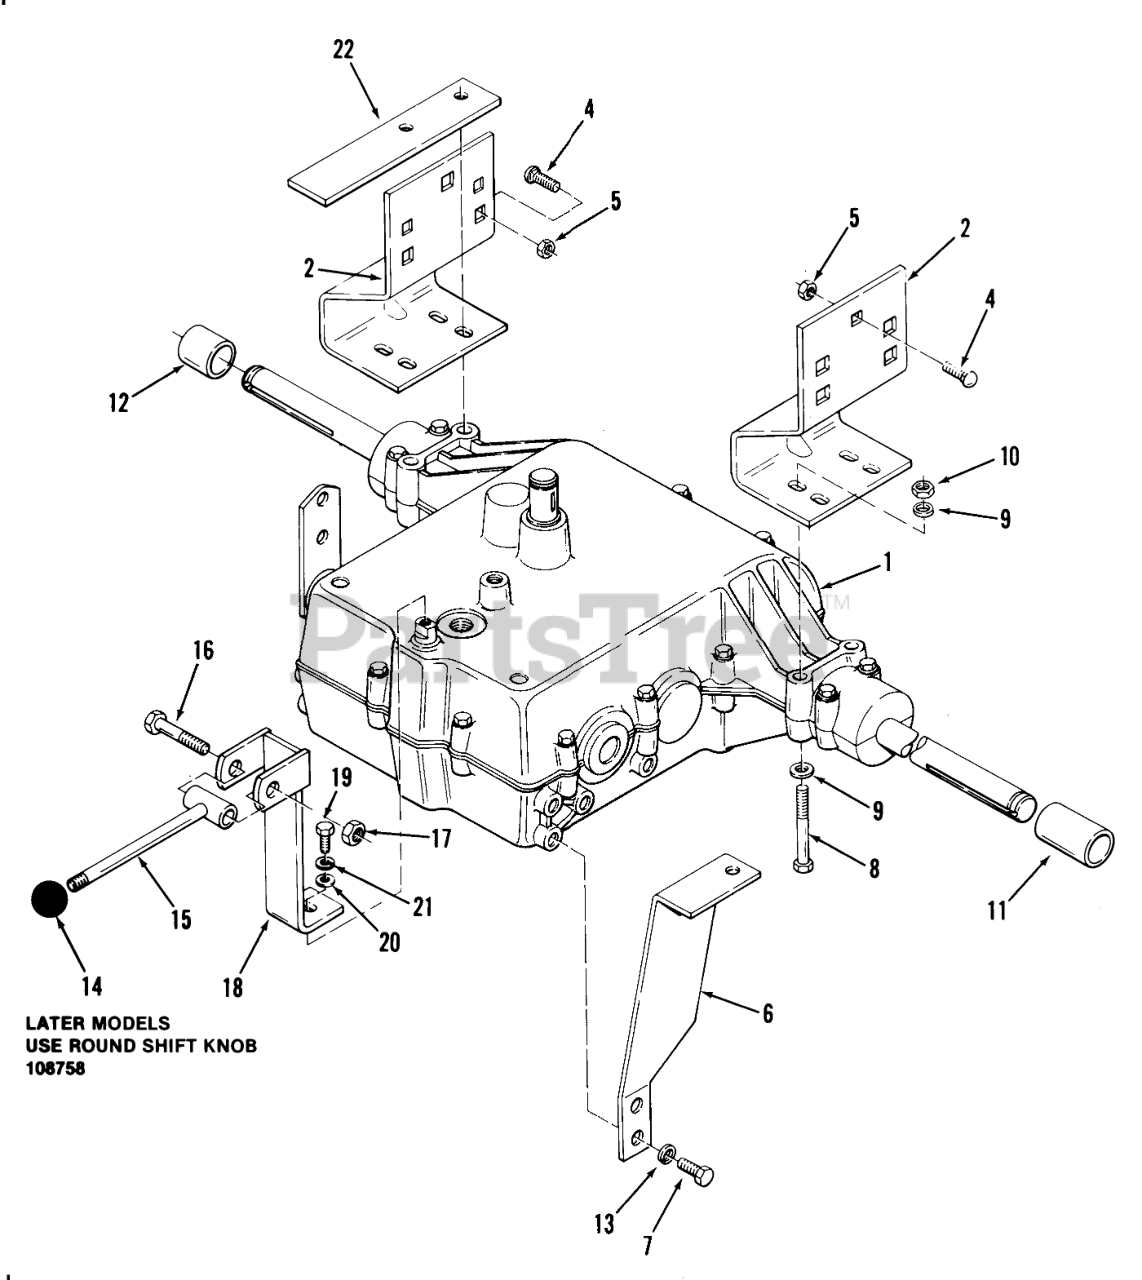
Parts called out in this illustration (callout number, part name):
1	Transmission-Peerless Model 801-002
2	BRKT-TRANS MOUNT R
4	CARRIAGE BOLT -4
5	Nut
6	TORQUE STRAP
7	Screw
8	HHCS
9	WASHER 5/16 SAE
10	Nut
11	SPACER-AXLE LH
12	SPACER-AXLE RH
13	Lockwasher
14	SHIFT KNOB
15	ASSY-UP SHIFT ROD
16	Bolt
17	Nut
18	Shift Lever-Lower
19	Bolt 1/4-28 X 7/8
20	WASHER
21	Washer
22	Brake Stop Bar
